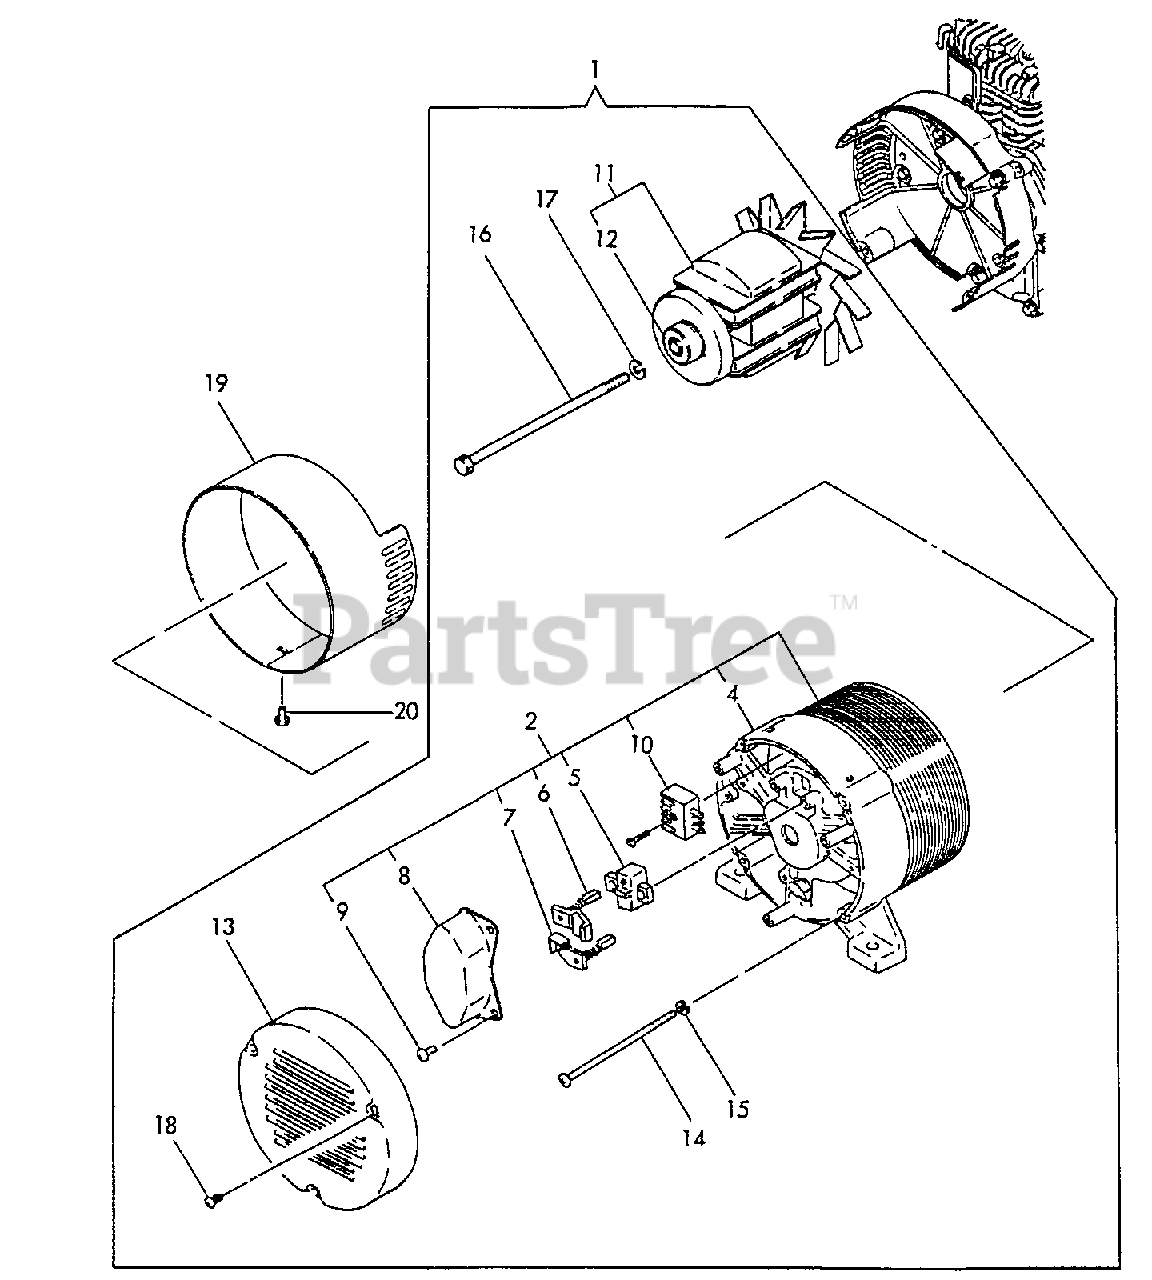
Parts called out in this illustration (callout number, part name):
1	GENERATOR 1.3 KVA
2	STATOR ASSY
4	COVER - REAR
5	HOLDER, BRUSH
6	BRUSH - ( + )
7	BRUSH - ( - )
8	A.V.R.
9	SCREW - 5×14
10	RECTIFIER
11	ROTOR ASSY
12	BEARING, BALL
13	COVER, END
14	BOLT
15	LOCKWASHER - 6
16	BOLT
17	LOCKWASHER - 8
18	SCREW - 4×8
19	BAND
20	BOLT - 6×8 -- PLATED
